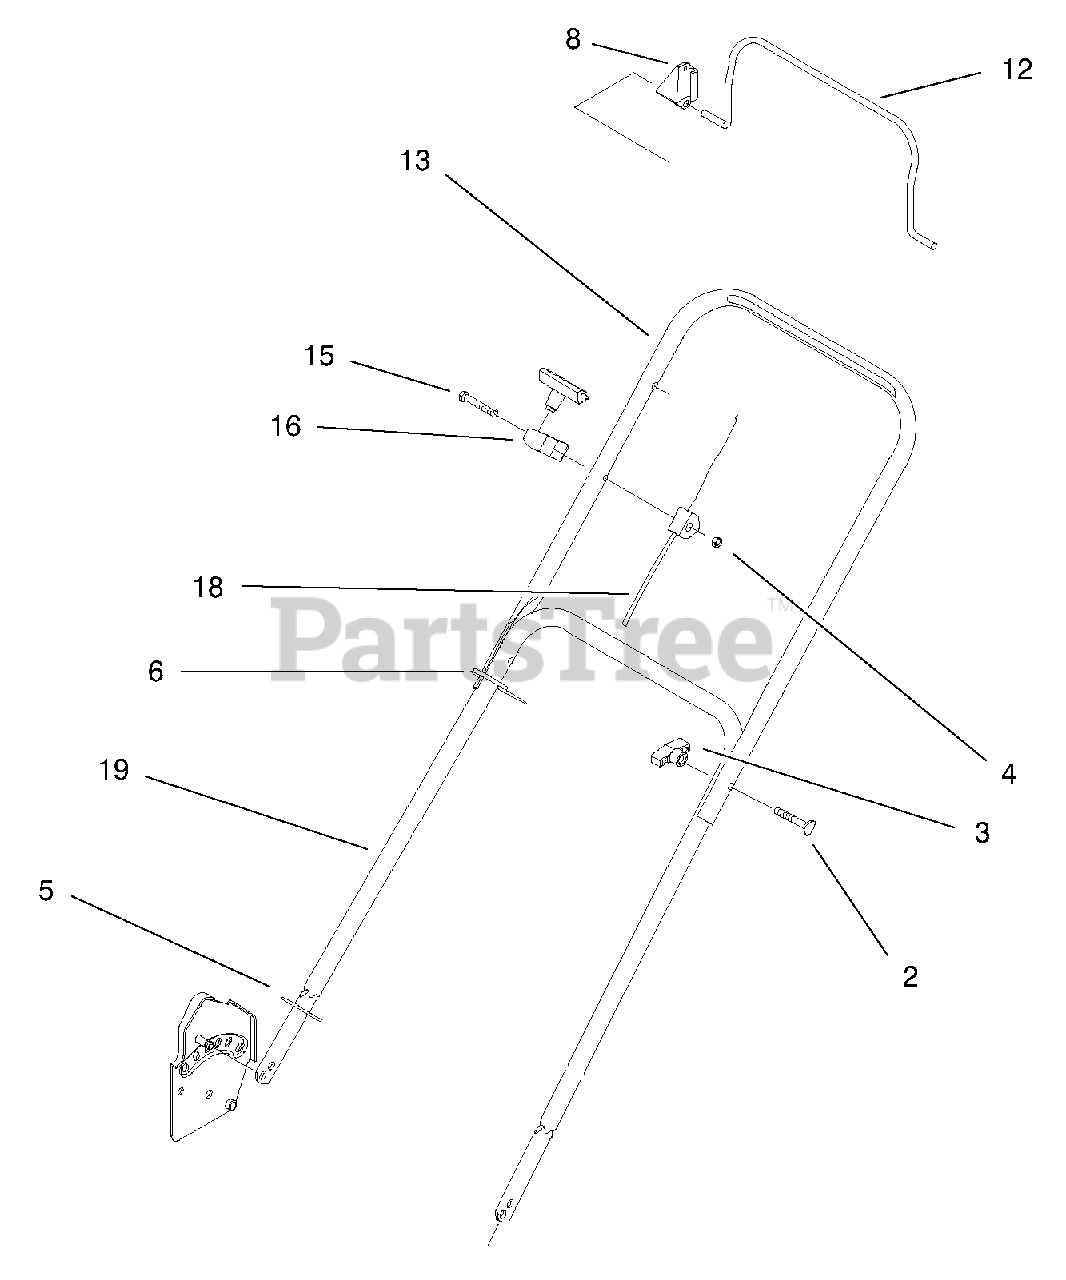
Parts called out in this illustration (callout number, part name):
2	Screw-HH
3	Knob-Handle
4	Nut-Lock NI
5	Guard-Handle
6	Strap-Tie, Small
8	Stop-Pivot
12	Bail-Brake
13	Handle-Upper
15	Screw-HH
16	Rope-Guide
18	Brake Cable ASM.
19	Section-lower Handle
